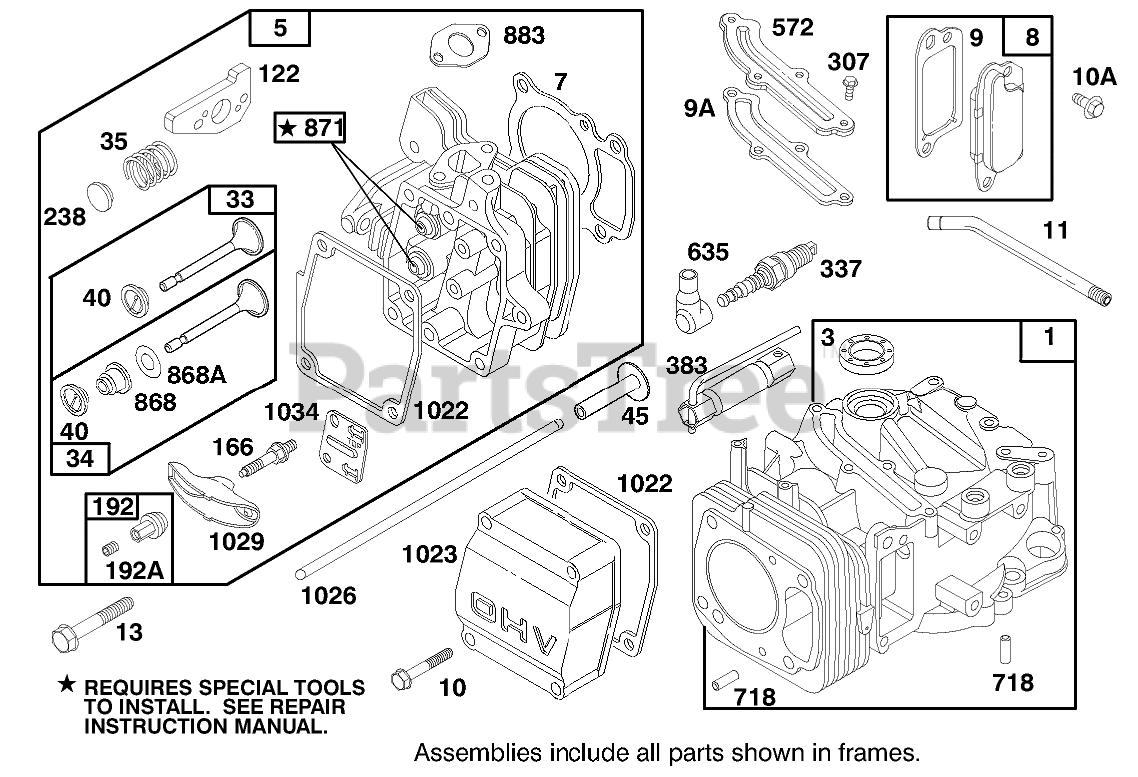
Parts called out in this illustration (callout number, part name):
1	CYLINDER ASSEMBLY
3	SEAL - OIL
5	CYLINDER HEAD
7	CYLINDER HEAD GASKET
8	Breather Assy
9	BREATHER GASKET
9A	GASKET-BREATHER
10	HEX HEAD SCREW
10A	HEX HEAD SCREW
11	TUBE - BREATHER
13	PLUG - PIPE
33	EXHAUST VALVE
34	INTAKE VALVE
35	VALVE SPRING
40	SPRING RETAINER
45	VALVE TAPPET
122	ADAPTER ASSEMBLY
166	ROCKER ARM STUD
192	NUT - HEX SPECIAL
192A	SCREW SET
238	VALVE CAP
307	SCREW - SEM
337	PLUG-SPARK
383	WRENCH-SPARK PLUG
572	BAFFLE - CYCLINDER
635	SPARK PLUG ELBOW
718	DOWEL - SLEEVE
868	ASM - VALVE SEAL
868A	Seal-Valve
871	Bushing-Guide
883	EXHAUST GASKET
1022	ROCKER COVER GASKET
1023	COVER - VALVE
1026	PUSH ROD
1029	ROCKER ARM
1034	PUSH ROD GUIDE
